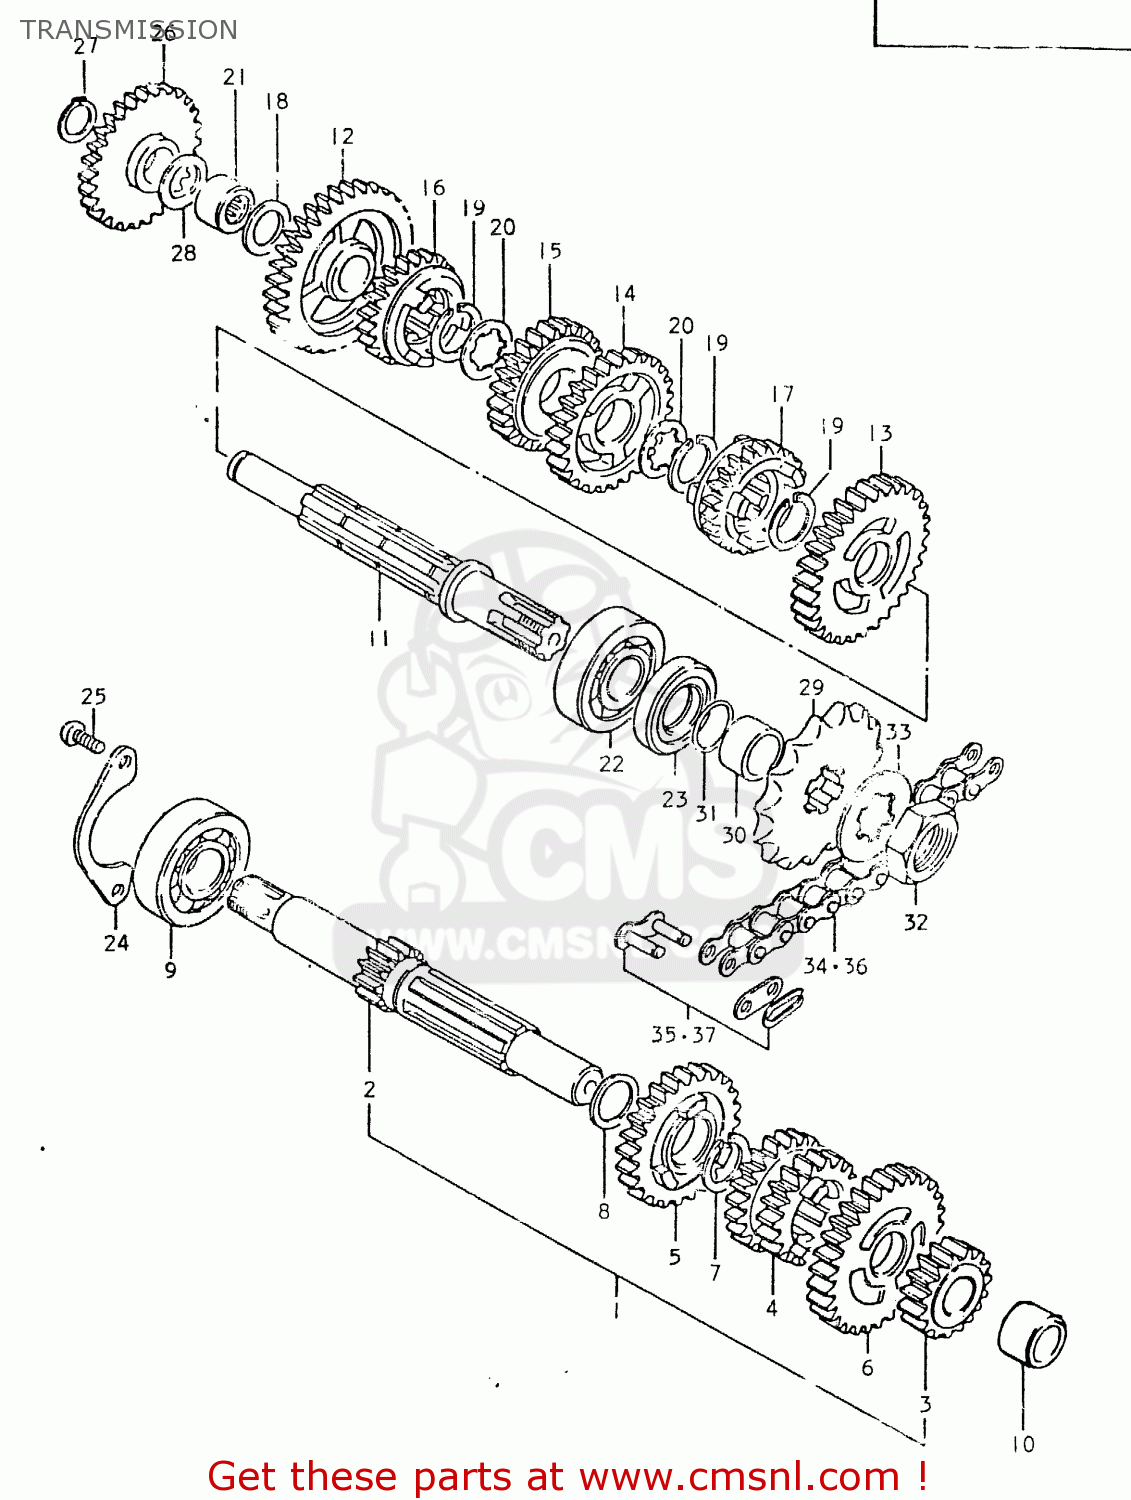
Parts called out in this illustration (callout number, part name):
1	SHAFT ASSEMBLY,COUNTER
2	SHAFT,COUNTER
3	GEAR,SECOND DRIVE
4	GEAR,THIRD/FOURTH DRIVE
5	GEAR,FIFTH DRIVE
6	GEAR,SIXTH DRIVE
7	CIRCLIP
8	WASHER
9	Bearing
10	BUSH(15X22X15)
11	SHAFT,GEAR SHIFT
12	GEAR,1ST DRIVEN
13	GEAR,SECOND DRIVEN
14	GEAR,THIRD DRIVEN
15	GEAR,FOURTH DRIVEN
16	GEAR,FIFTH DRIVEN
17	GEAR,SIXTH DRIVEN
18	WASHER,THRUST
19	CIRCLIP
20	WASHER,LOCK
21	BEARING(15X22X12)
22	Bearing
23	SEAL,OIL(25X40X7)
24	RETAINER,CNTR SHAFT BEARING
25	SCREW 6X12
26	GEAR,KICK STARTER IDLE
27	CIRCLIP,15MM
28	WASHER,THRUST
29	SPROCKET,ENGINE
30	SPACER(20X25X12.5)
31	O RING(D:1,ID:19.5)
32	NUT
33	WASHER,LOCK
34	CHAIN ASSEMBLY,DRIVE
35	JOINT ASSEMBLY,CHAIN
36	CHAIN ASSEMBLY,DRIVE
37	JOINT ASSEMBLY,CHAIN
